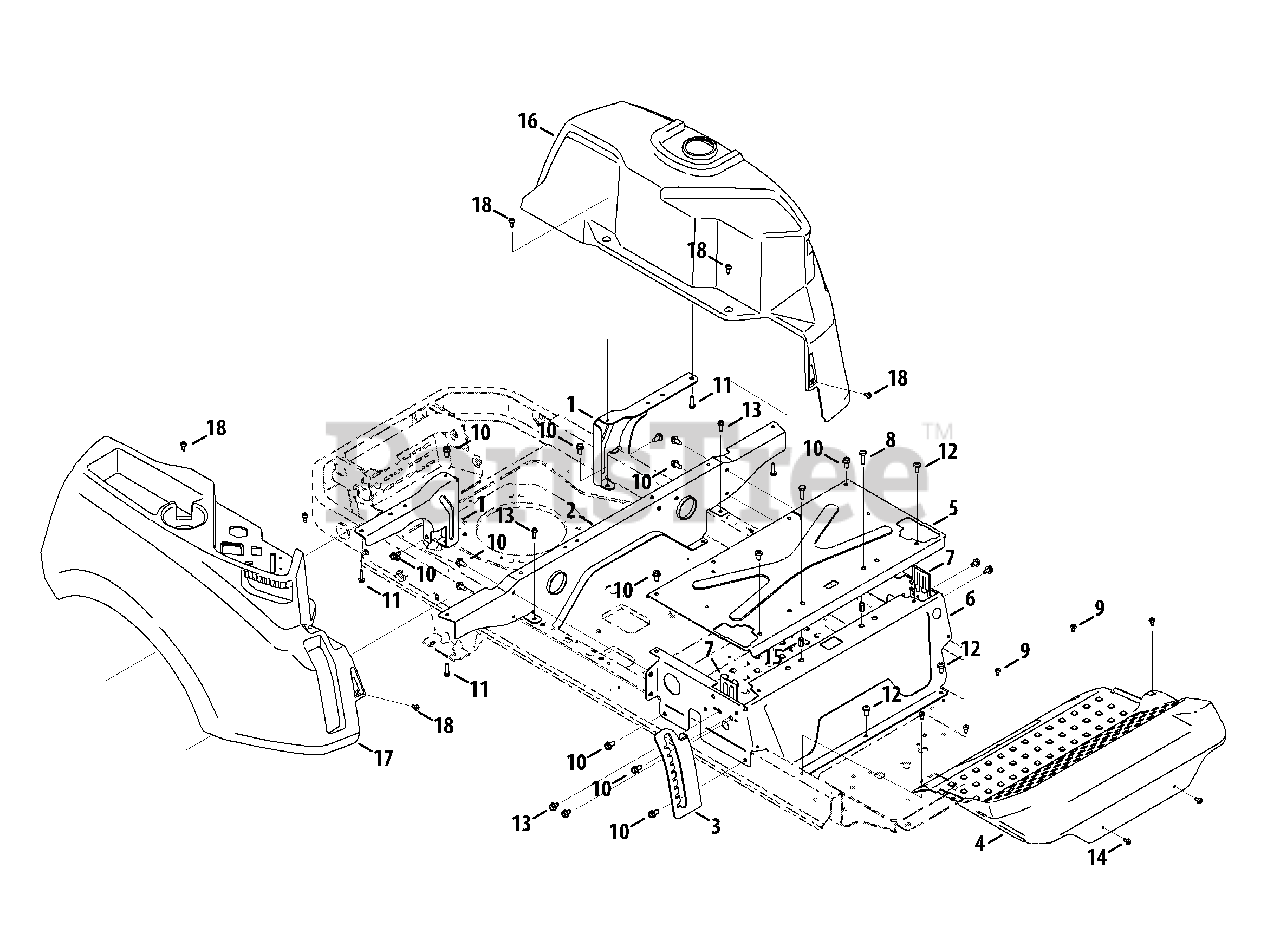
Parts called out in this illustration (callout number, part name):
1	Rear Tank Bracket
2	Rear Seatbox Brace
3	Height Index Bracket
4	Floor Board
5	Seatbox Plate
7	Lapbar Brace Bracket
8	Hex Cap Screw, 5/16-18 x 1.00
9	Self Tapping Screw, 1/4-20 x .50
10	Hex Washer Screw, 5/16-18 x .750
11	Hex Washer Screw, 5/16-14 x 1.00
12	Self Tapping Screw, 5/16-18 x .750
13	Hex Washer Screw, 5/16-18 x .50
14	Screw, Self-Tapping, 5/16-18, 0.750
15	Nut, 5/16-18
16	LH Console
17	RH Console
18	Shoulder Screw, 1/4-20
